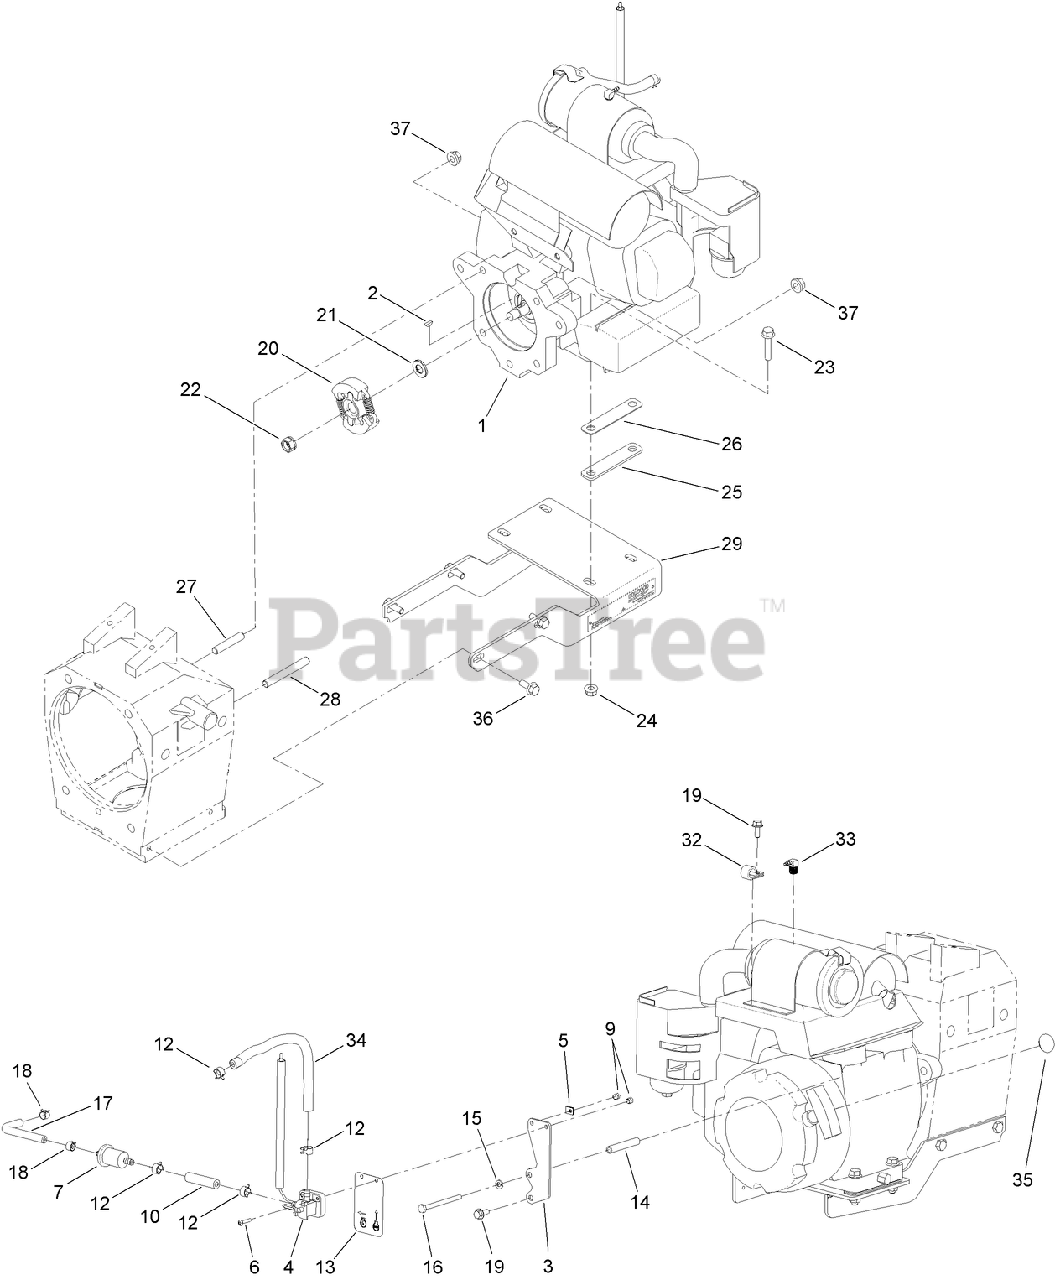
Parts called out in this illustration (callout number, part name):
1	ENGINE-HONDA, GX120
2	KEY-WOODRUFF
3	PLATE-SWITCH, STOP
4	FUEL SHUT OFF VALVE ASM
5	CLAMP
6	SCREW-HSBH
7	FILTER-FUEL
9	NUT-LOCK
10	HOSE-FUEL
12	CLAMP-HOSE
13	HANG TAG-RUN, STOP
14	TUBE-SWITCH, STOP
15	WASHER-LOCK, SPRING
16	SCREW-HH
17	HOSE-FUEL
18	CLAMP-HOSE
19	SCREW-HHF
20	CLUTCH-FRICTION
21	SPACER-CLUTCH
22	NUT-HEX FLANGE
23	SCREW-HHF
24	NUT-HF
25	SHIM-ENGINE (11GA)
26	SHIM-ENGINE (16GA)
29	SUPPORT-ENGINE
32	CLAMP-R
33	ELBOW-90
34	Fuel Line
35	PLUG-RUBBER
36	SCREW-HHF
